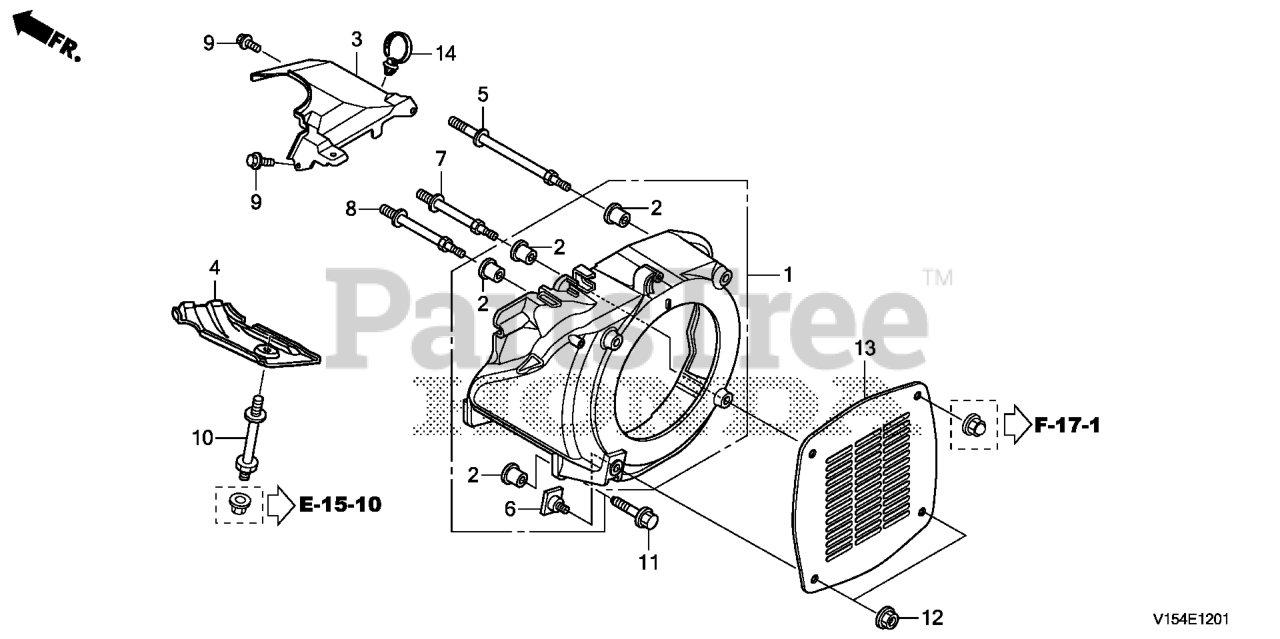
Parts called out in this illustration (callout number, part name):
1	COVER, FAN *R280* (POWER RED)
2	COLLAR, FAN COVER (Honda Code 5580527). (N/A: SEE ASSEMBLY)
3	SHROUD (UPPER)
5	BOLT, STUD (SEL)
6	BOLT, SPECIAL (6MM)
7	BOLT, STUD
8	BOLT B, STUD
9	BOLT, FLANGE (6X12) (CT200)
10	BOLT, SHROUD (LOWER)
11	BOLT, FLANGE (6X25) Use up to Engine SN 2056819.
12	NUT, FLANGE (6MM)
13	GUARD, FAN
14	CLIP, HARNESS BAND (145MM) (BLACK)
